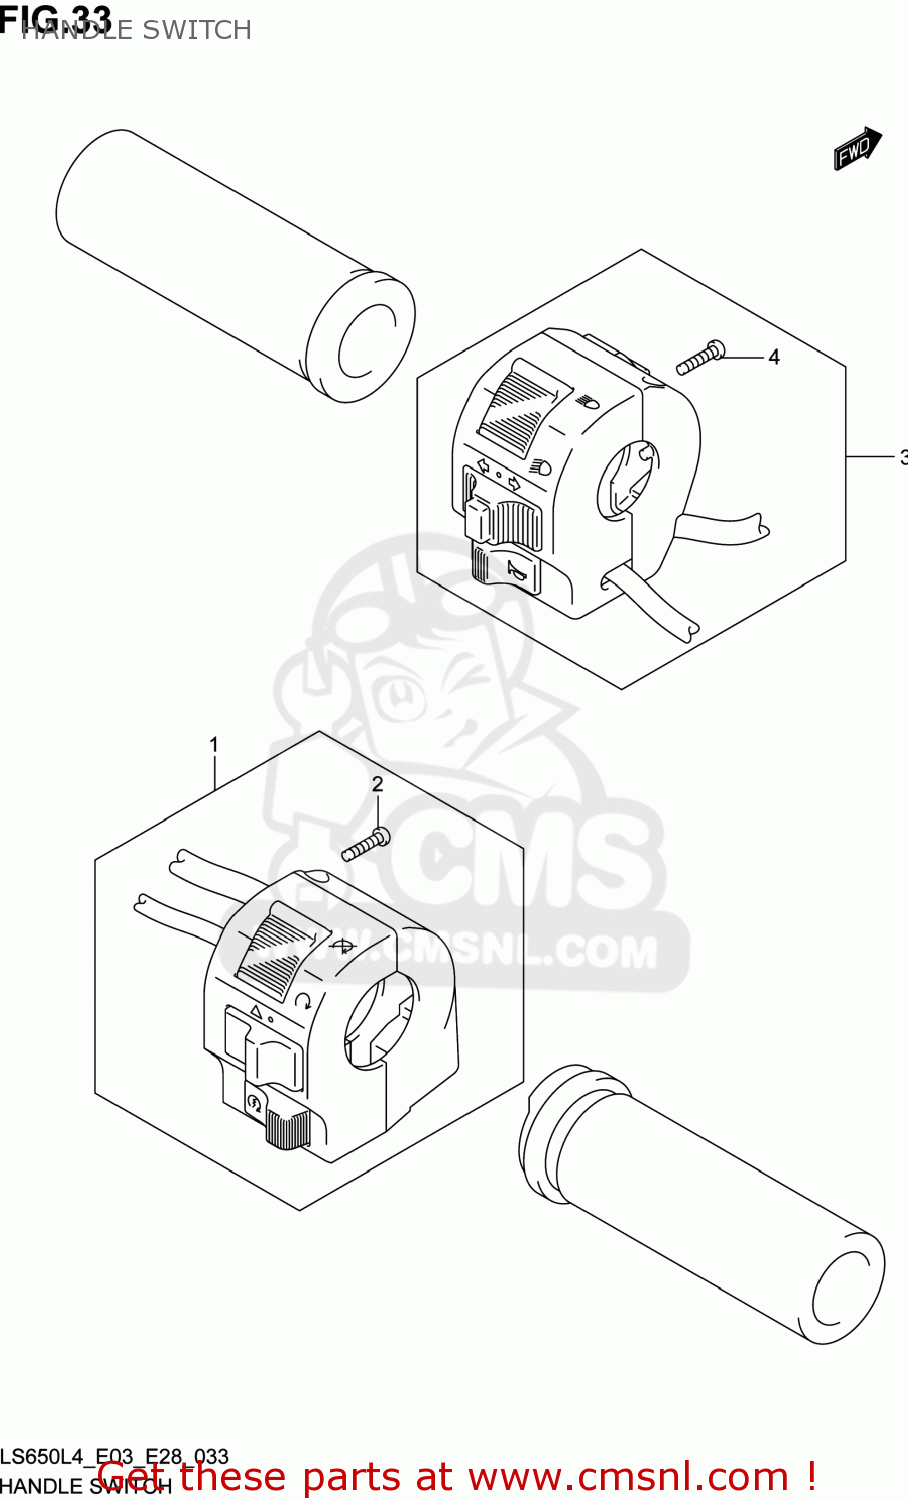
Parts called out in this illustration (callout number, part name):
1	SWITCH ASSY,HANDLE,R
2	SCREW
3	SWITCH ASSY,HANDLE,L
4	SCREW
